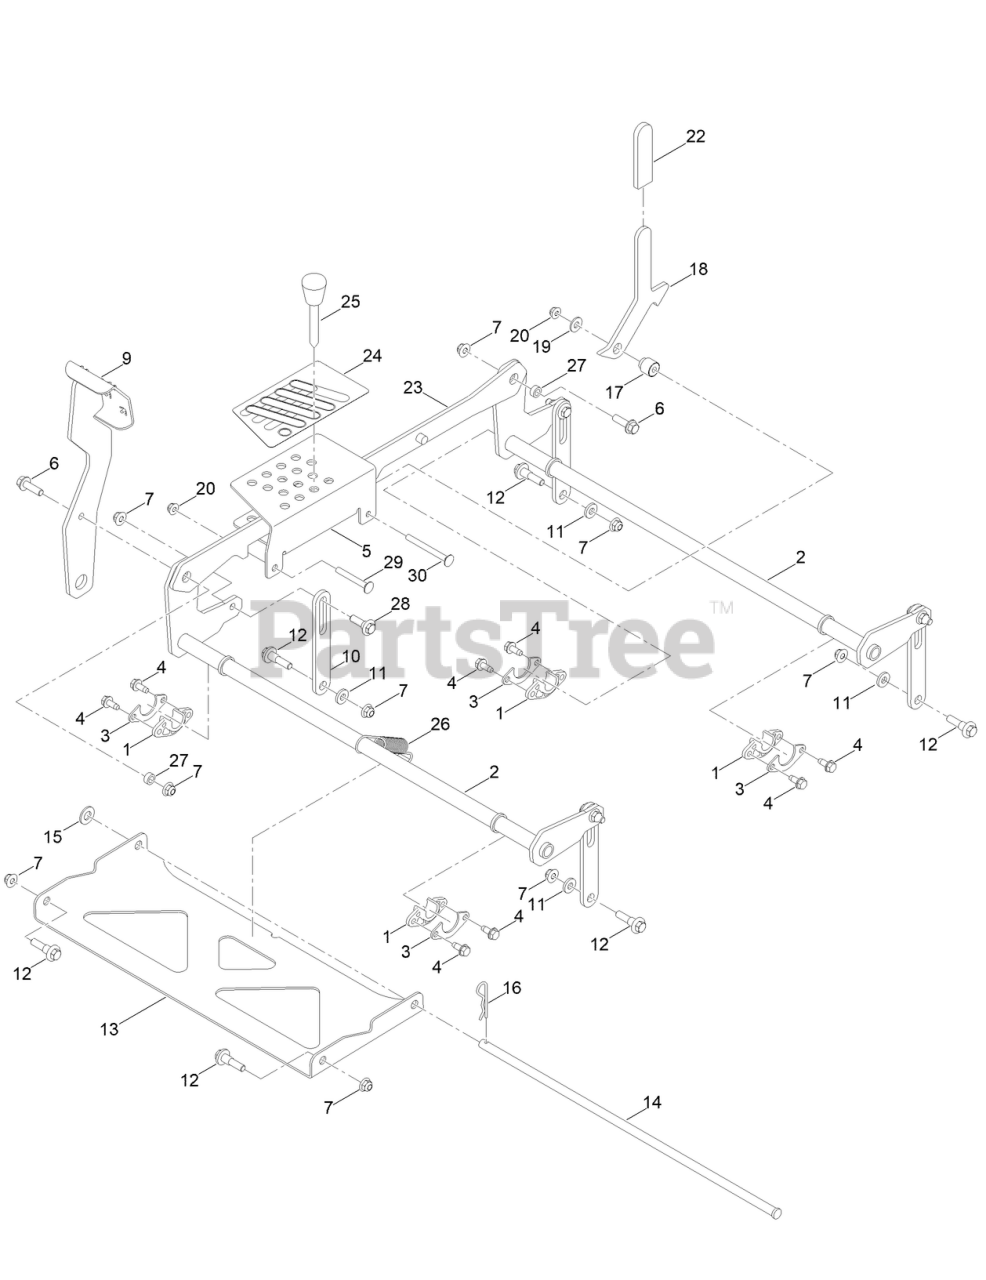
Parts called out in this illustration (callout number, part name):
1	BEARING-FLANGE
3	GUSSET-DECK LIFT
4	SCREW-HWHTF
5	BRACKET-HOC
6	SCREW-HHF
7	NUT-HF, NI
11	SPACER-HUB, BLOWER
12	BOLT-SHOULDER
13	PAN-DECK PIVOT
14	PIN-DECK
15	WASHER-FLAT
16	PIN-HAIR
17	SPACER-STEPPED
18	PLATE-TRANSPORT LOCK
19	WASHER-PLAIN
20	NUT-HF
22	GRIP-HANDLE
24	DECAL-HOC
25	HOC PIN ASM
26	SPRING-EXTENSION
27	SPACER
28	SCREW-SHOULDER, HWH
29	BOLT-CARR
30	SCREW-CARR
